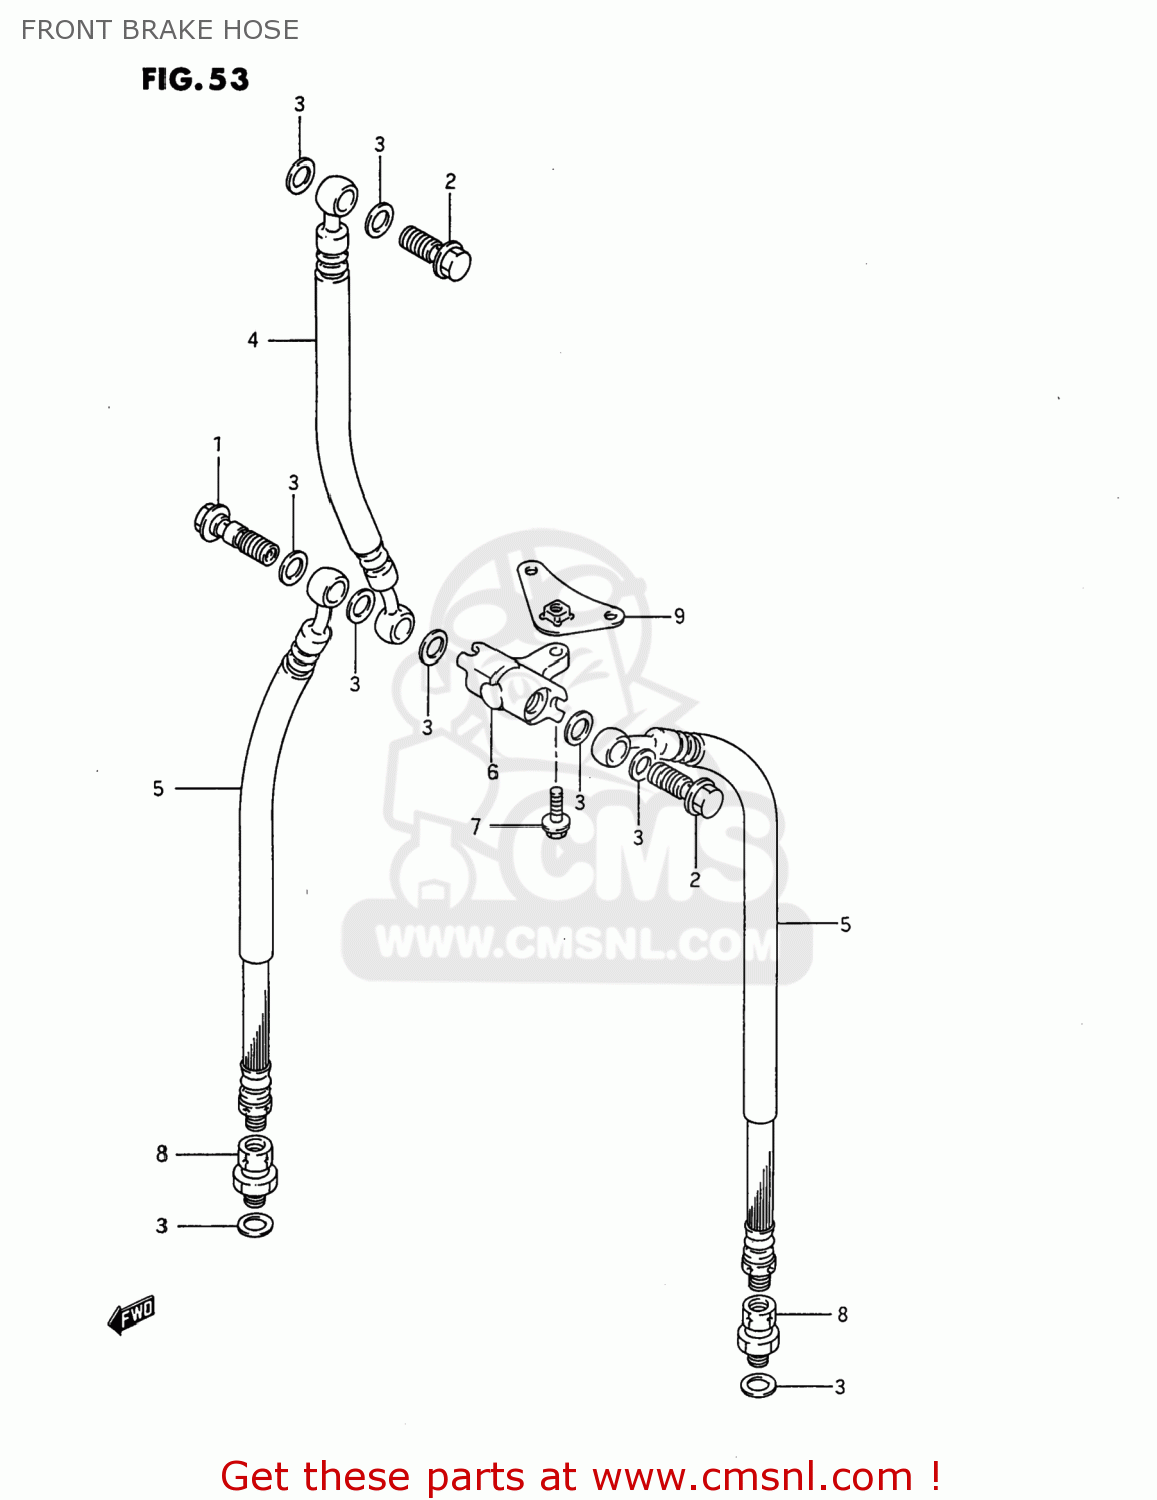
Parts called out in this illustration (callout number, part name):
1	BOLT UNION
2	BOLT UNION
3	WASHER(10X15X1.5)
4	HOSE,FR BRAKE NO.1
5	HOSE,FR BRAKE NO.2
6	JOINT,BRAKE HOSE
7	BOLT
8	ADAPTER,BRAKE HOSE
9	PLATE,FRONT BRAKE JOINT
